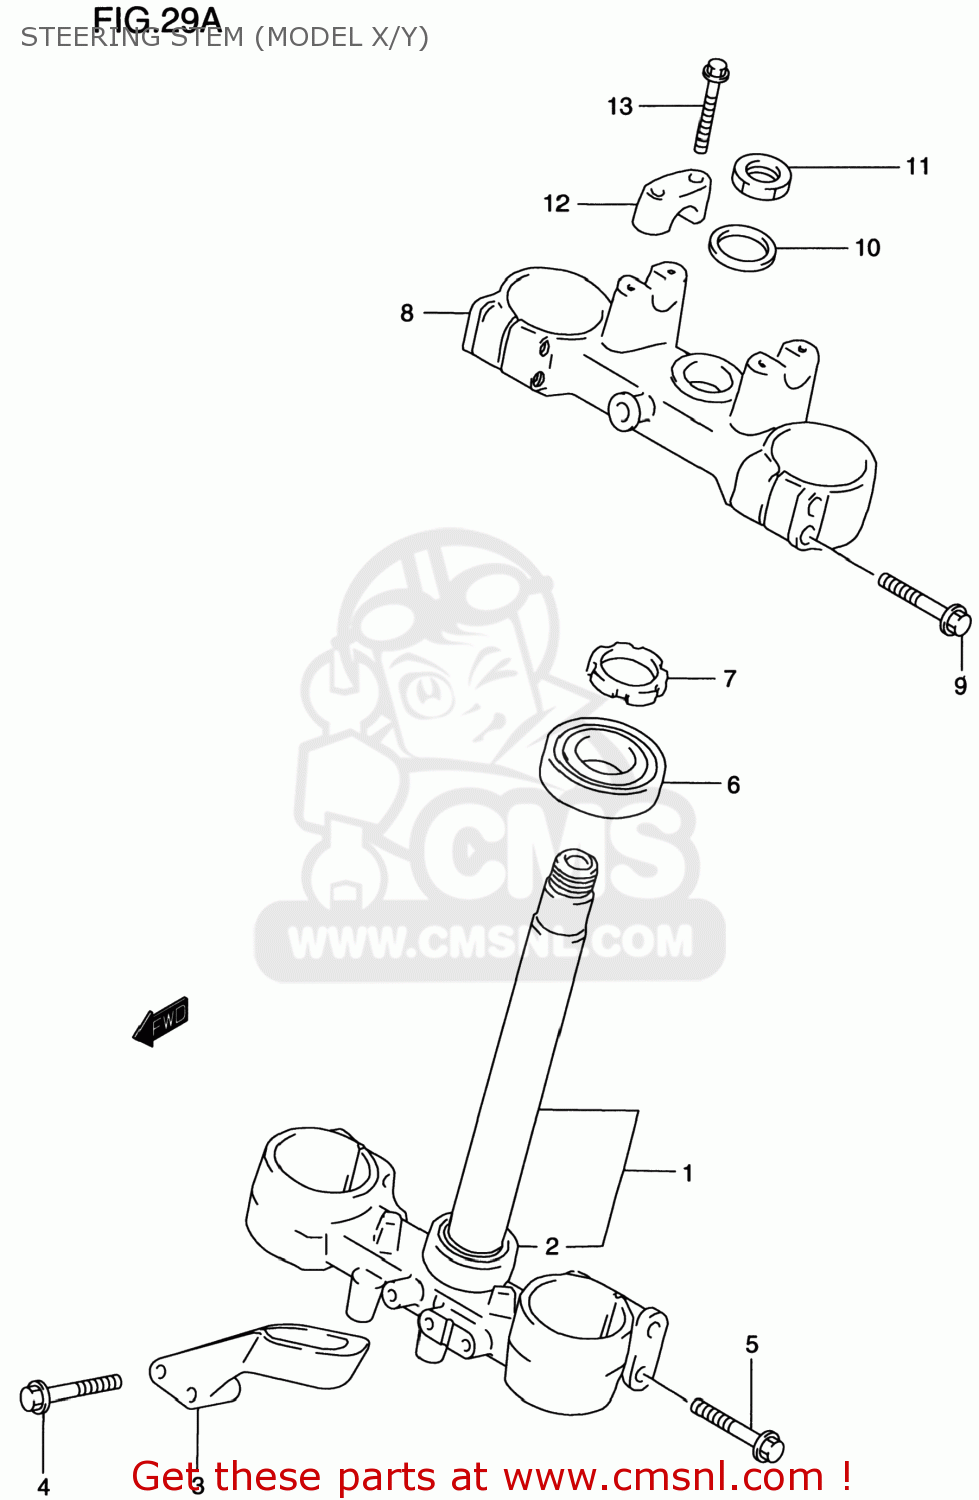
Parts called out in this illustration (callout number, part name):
1	BRACKET,FR FORK UNDER
2	BEARING(30X52X16)
3	BRACKET,BRAKE HOSE
4	BOLT,HOSE BRACKET(6X40)
5	BOLT,STEM 8X45
6	BEARING(30X52X16)
7	NUT,STEERING
8	BRACKET,FR FORK UPR
9	BOLT,STEM 8X45
10	WASHER,STEM HEAD
11	NUT,STEM HEAD
12	HOLDER,HANDLEBAR
13	BOLT,HANDLE HOLDER(8X35)
